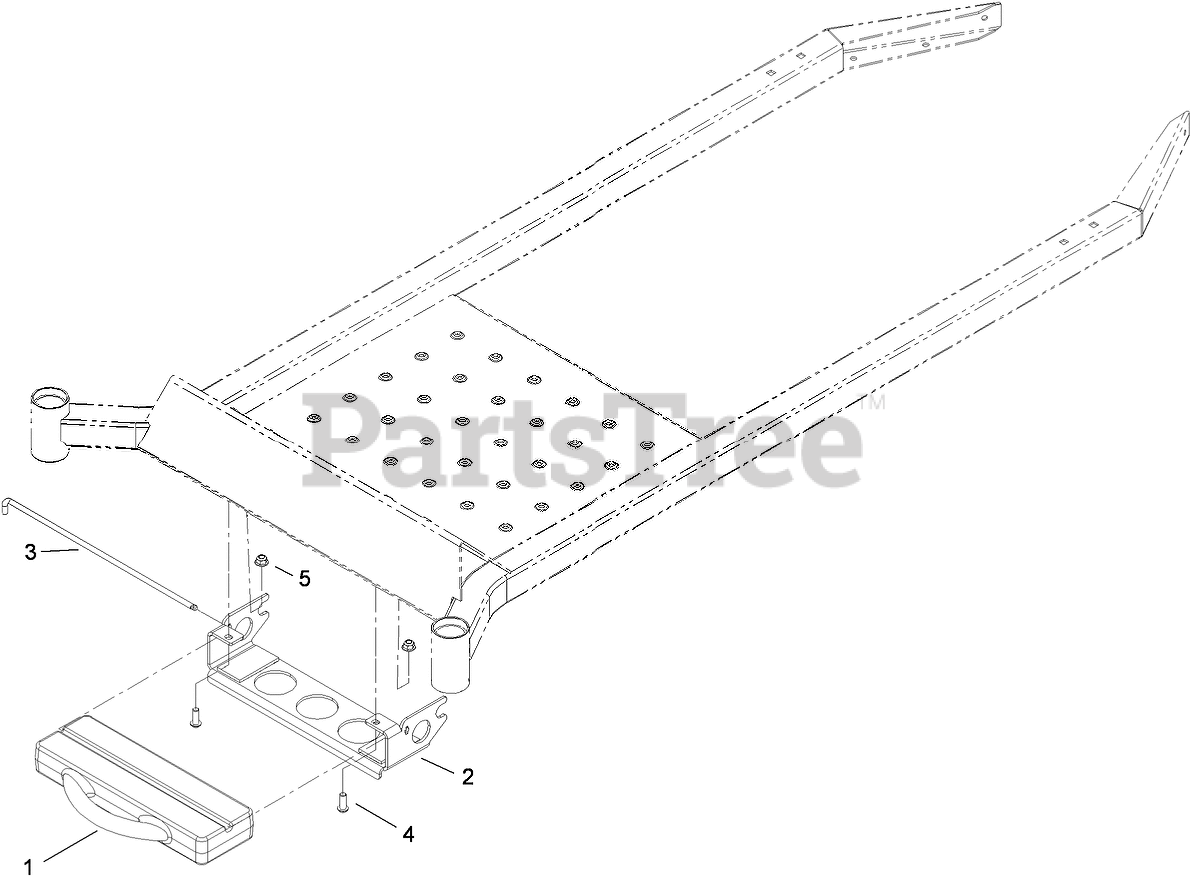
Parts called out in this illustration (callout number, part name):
1	WEIGHT-35 POUND
2	BRACKET ASM
3	PIN-WEIGHT
4	SCREW-HSBH
5	NUT-HF, NI
